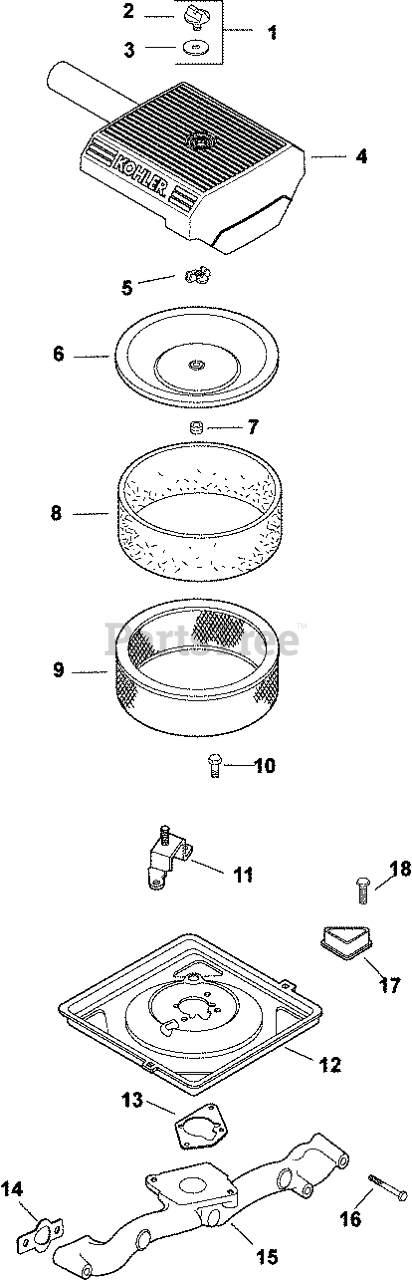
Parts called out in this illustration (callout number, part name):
1	KIT, KNOB W/SEAL
2	KNOB, COVER
4	COVER, AIR CLEANER
5	NUT, WING
6	COVER, INNER AIR CLEANER
7	SEAL, INNER AIR CLEANER
8	ELEMENT, PRECLEANER (LOW)
9	ELEMENT, AIR CLEANER - Also available Retail Packaged 47 883 03-S1 Air Filter Kit
10	SCREW,FLG THD FRM M6X1.0X20-(#25086396S)
11	BRACKET,AIR CLEANERBASE-USE 24 126 206-S
12	BASE ASSY, AIR CLEANER-USE 24 094 89-S
13	GASKET, AIR CLEANER BASE
14	GASKET, INTAKE MANIFOLD USE 24 041 79-S
15	MANIFOLD, METAL INTAKE
16	SCREW, FLG M6X1.0X55
17	COVER, BLOWER HOUSING USE 24 096 160-S
18	SCREW, WSH HD TAP #8-18X1/2"
